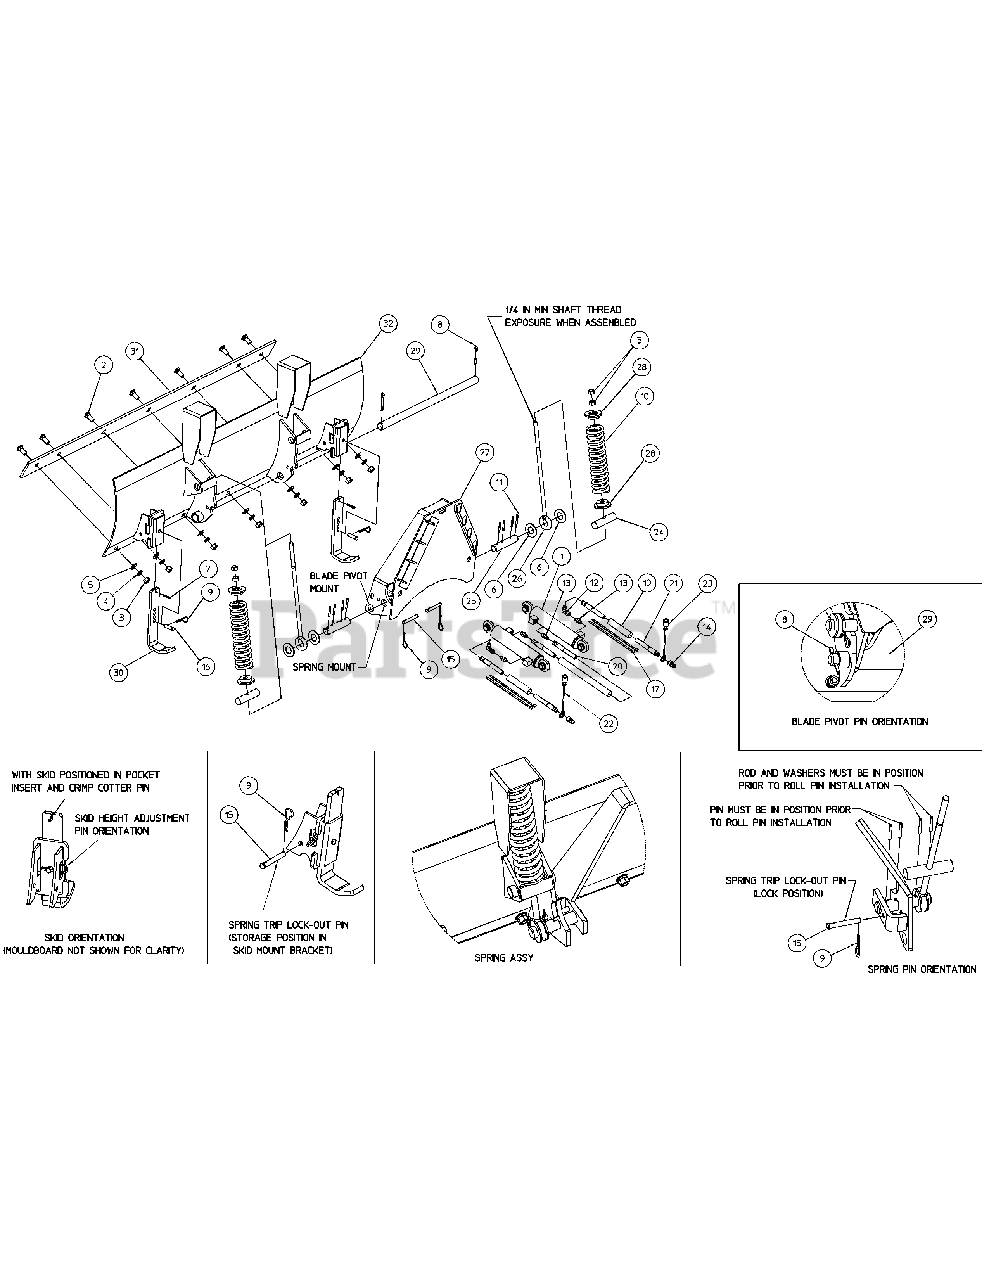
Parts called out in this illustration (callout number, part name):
1	ASSY-HYD CYLINDER
2	CARRIAGE BOLT 5/8-11X1.5
3	NUT HEX 5/8-11
4	LOCK WASHER 5/8
5	FLAT WASHER 5/8 HARDENED
6	FLAT WASHER 1-1/4 SAE
7	COTTER PIN 1/4 X 1
8	COTTER PIN 5/16 X 2-1/2
9	HAIR PIN CLIP
10	COMPRESSION SPRING
11	ROLL PIN 1/4 X 2
13	UNION STRAIGHT
14	COUPLER NOSE
15	CLEVIS PIN 1/2 X 3-1/2
16	CLEVIS PIN 1/2 X 1-3/4
17	PLASTIC TIE
18	HYDRAULIC FLUID
19	HOSE SLEEVE 1 ID X 89
20	HYD HOSE WITH SLEEVE 1/4 X 20
21	HYS HOSE 1/4 X 85
22	DUST CAP YELLOW
23	DUST CAP RED
24	SPRING PIVOT PIN
26	EYE BOLT (SPRING MOUNT)
27	MOUNT WELDMENT
28	SPRING CAP WELDMENT
29	BLADE PIVOT PIN
30	SKID PLATE
31	66" CUTTING EDGE PLATE
32	66" MOULDBOARD WITH DECALS
